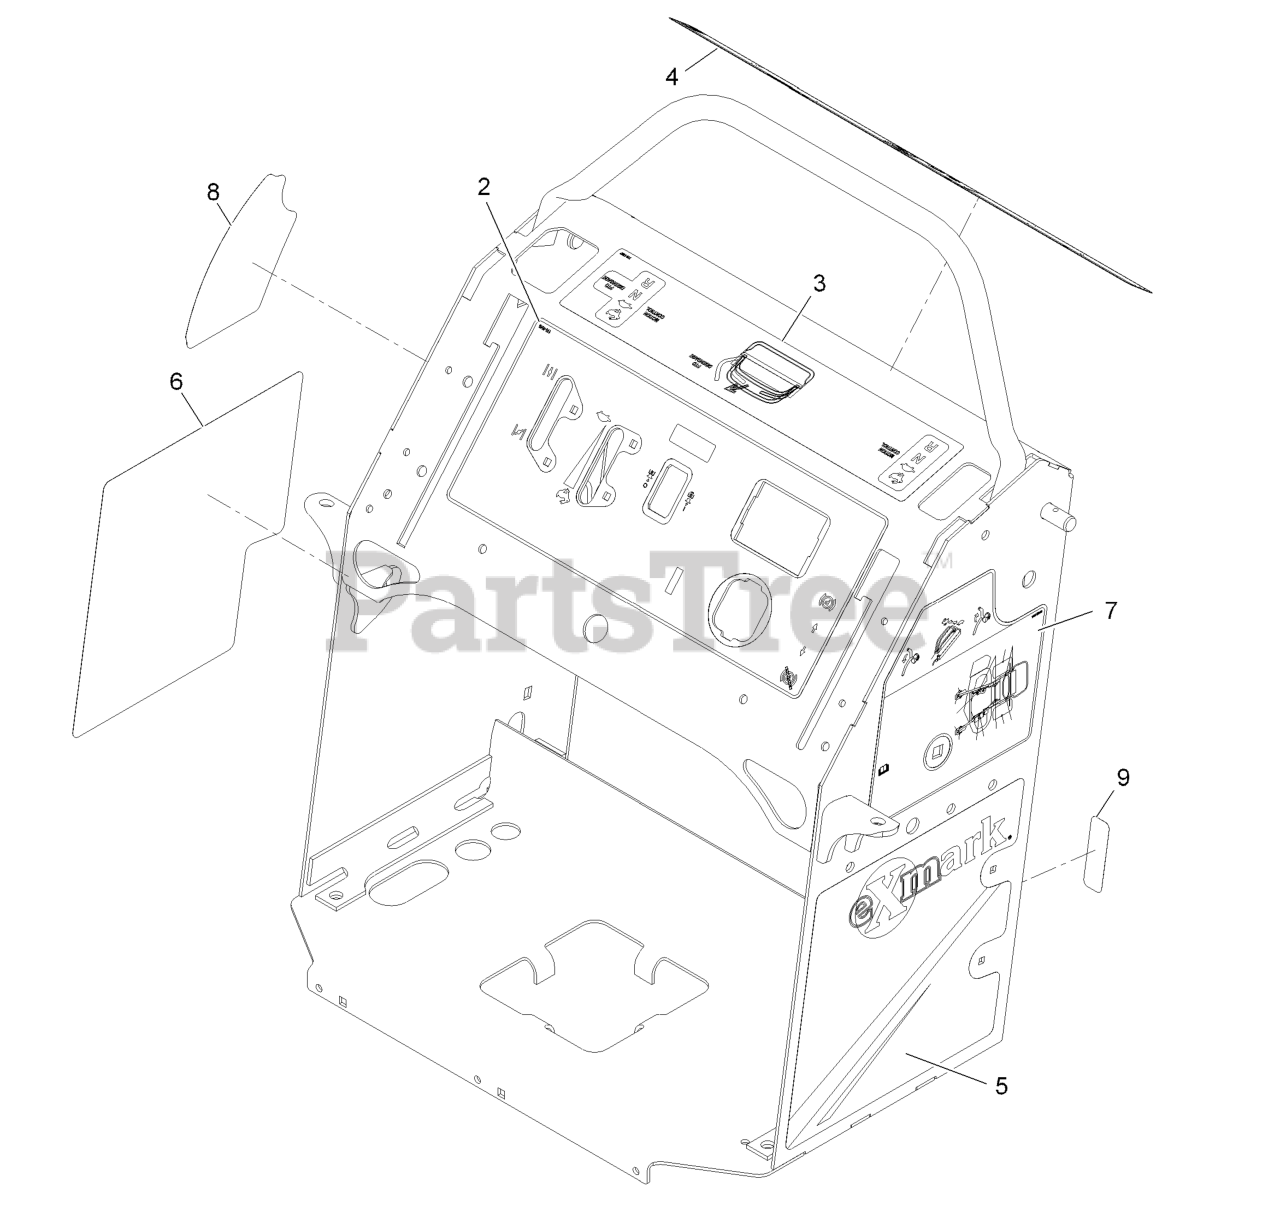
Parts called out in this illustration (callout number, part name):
2	DECAL-CONTROL PANEL
3	DECAL-MOTION CONTROL
4	DECAL-WARNING
5	DECAL-LH PANEL
6	DECAL-RH PANEL
7	DECAL-SERVICE AID
8	DECAL-HEIGHT OF CUT
9	DECAL-FUSE
